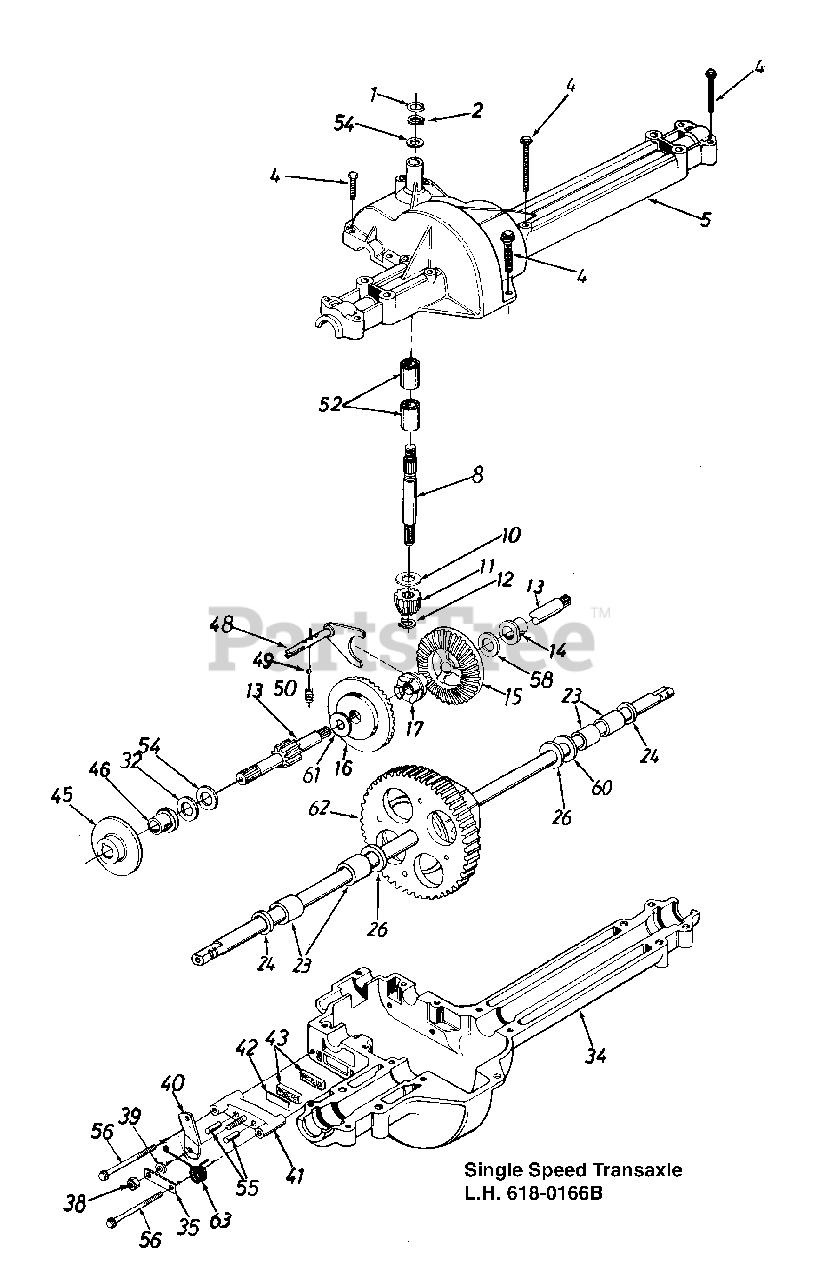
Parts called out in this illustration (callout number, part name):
1	Wire Ring
2	Retaining Ring
4	Tap Scr. 1/4
5	Upper Housing
8	Input Shaft
10	Thrust Washer 5/8" I.D. x 1.25" Lg.
11	Pinion Input 14T
12	Retaining Ring
13	Drive Shaft L.H. Brake
14	Flange Brg. 5/8" I.D. x 3/4" Lg.
15	Bevel Gear 42T Small I.D.
16	Bevel Gear 42T Large I.D.
17	Clutch Collar
23	Sleeve Bearing 3/4" I.D. x 1.0"
24	Oil Seal 3/4" I.D.
26	Flat Washer .760" I.D. x 1.5" O.D.
32	Thrust Washer 5/8" x 1" x .025"
34	Lower Housing
35	Anti-Rotation Brkt.
38	Hex Nut 5/16-24 Thd.
39	Flat Washer .344" I.D. x .875" O.D.
40	Actuating Arm
41	Brake Yoke
42	Puck Plate
43	Brake Puck
45	Brake Disc
46	Flange Bearing 5/8" I.D. x 15/16"
48	Shift Fork Ass'y.
49	Ball Detent .250" Dia.
50	Spring Detent
52	Needle Brg. 5/8" I.D. x 1/2" Lg.
54	Flat Washer 5/8" I.D. x 1" O.D.
55	Actuating Pin 5/16" Dia.
56	Hex Wash Hd. Self-Tap Scr.
58	Flat Washer 5/8" I.D. x 1" O.D. x
60	Flat Washer .76" x 1.5" x .010"
61	Thrust Washer
62	Differential Ass'y.
63	L.H. Brake Spring
